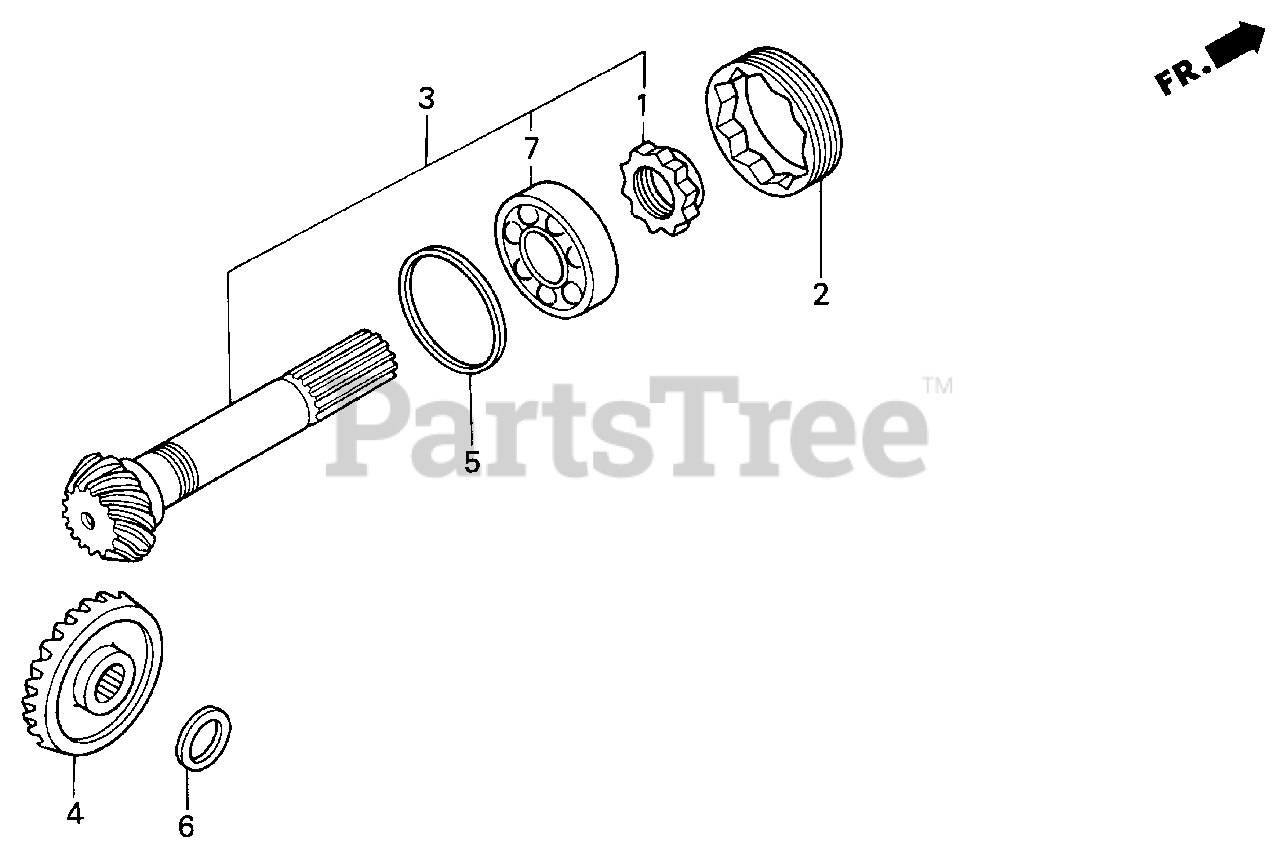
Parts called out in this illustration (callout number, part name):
1	NUT, LOCK (22MM)
2	NUT, LOCK (52MM)
3	SHAFT, INPUT
4	GEAR, BEVEL
5	SHIM A, PINION GEAR (1.25MM)
5	SHIM B, PINION GEAR (1.30MM)
5	SHIM C, PINION GEAR (1.35MM)
5	SHIM D, PINION GEAR (1.40MM)
5	SHIM E, PINION GEAR (1.45MM)
5	SHIM F, PINION GEAR (1.50MM)
5	SHIM G, PINION GEAR (1.55MM)
5	SHIM H, PINION GEAR (1.60MM)
5	SHIM I, PINION GEAR (1.65MM)
5	SHIM J, PINION GEAR (1.70MM)
6	SHIM A, BEVEL GEAR (3.35MM)
6	SHIM B, BEVEL GEAR (2.40MM)
6	SHIM C, BEVEL GEAR (2.45MM)
6	SHIM D, BEVEL GEAR (2.50MM)
6	SHIM E, BEVEL GEAR (2.55MM)
6	SHIM F, BEVEL GEAR (2.60MM)
6	SHIM G, BEVEL GEAR (2.65MM)
7	BEARING, RADIAL BALL (62/22)
